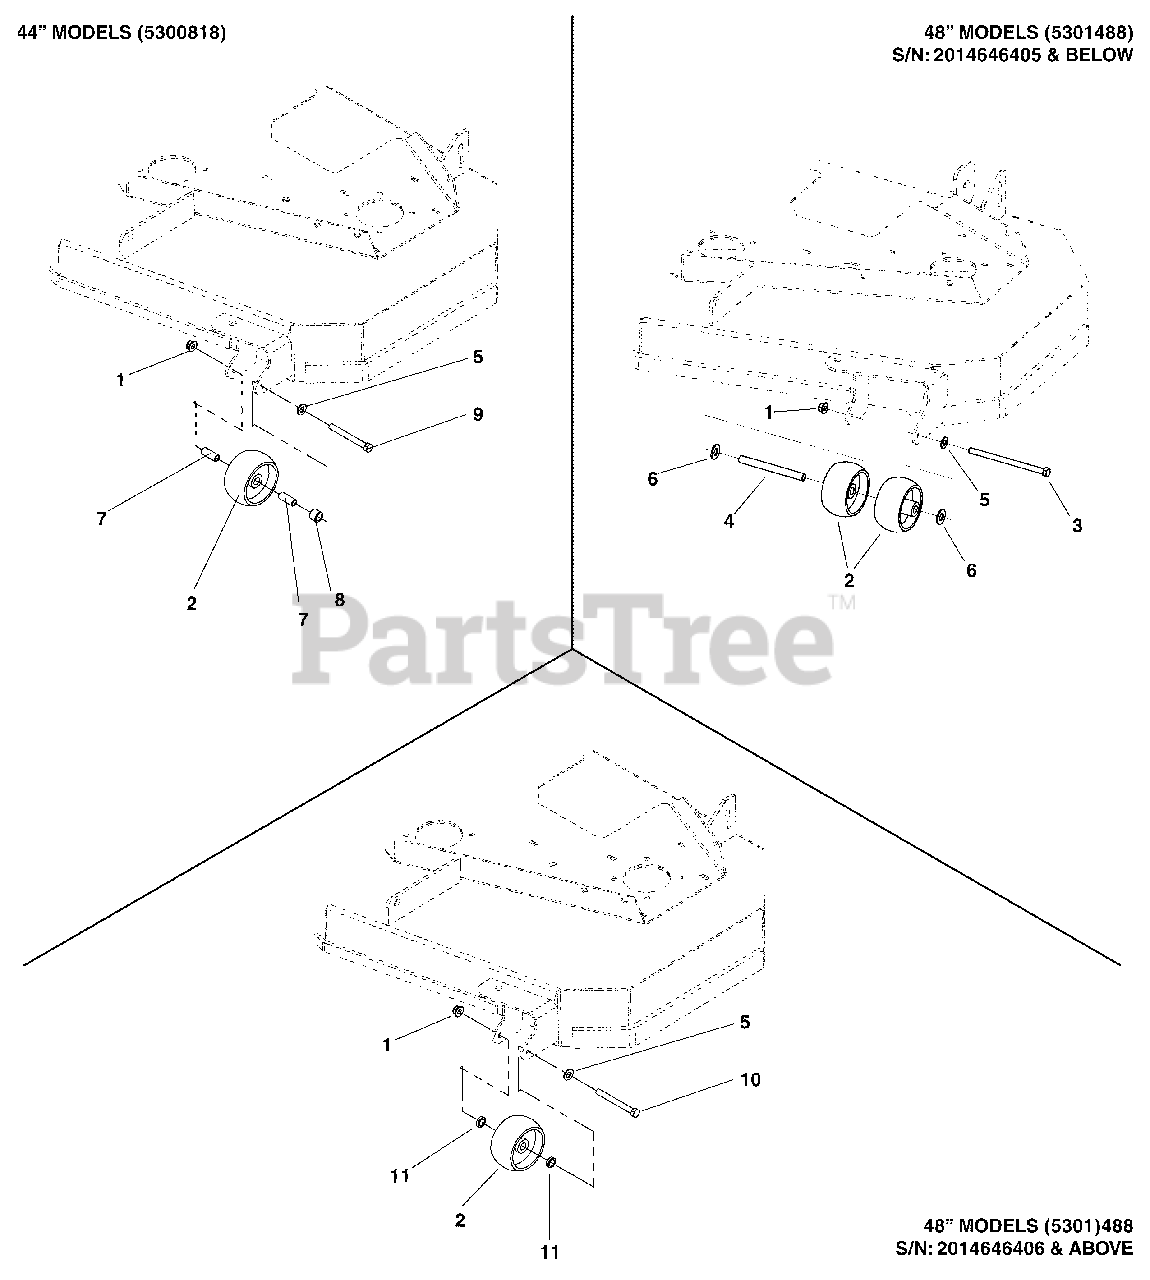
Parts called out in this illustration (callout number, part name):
1	NUT, 3/8-16 HEX NYLOCK FLANGE
2	WHEEL- 2.00 WIDE 3.92 DIA 0.531ID POLY
3	BOLT, 3/8-16 X 6 GD5 YZ
4	SPACER, .38 X .50 X 5.06
5	WASHER, 3/8 SAE
6	WASHER, 1/2 SAE
7	SPACER, .38 X .50 X 1.25
8	SPACER, .51 X .75 X .56
9	BOLT, 3/8-16 X 3-1/2 GD5 YZ
10	BOLT-WHEEL 3/8-16X2.7
11	WASHER (0.51IDX0.87ODX.06THK)
